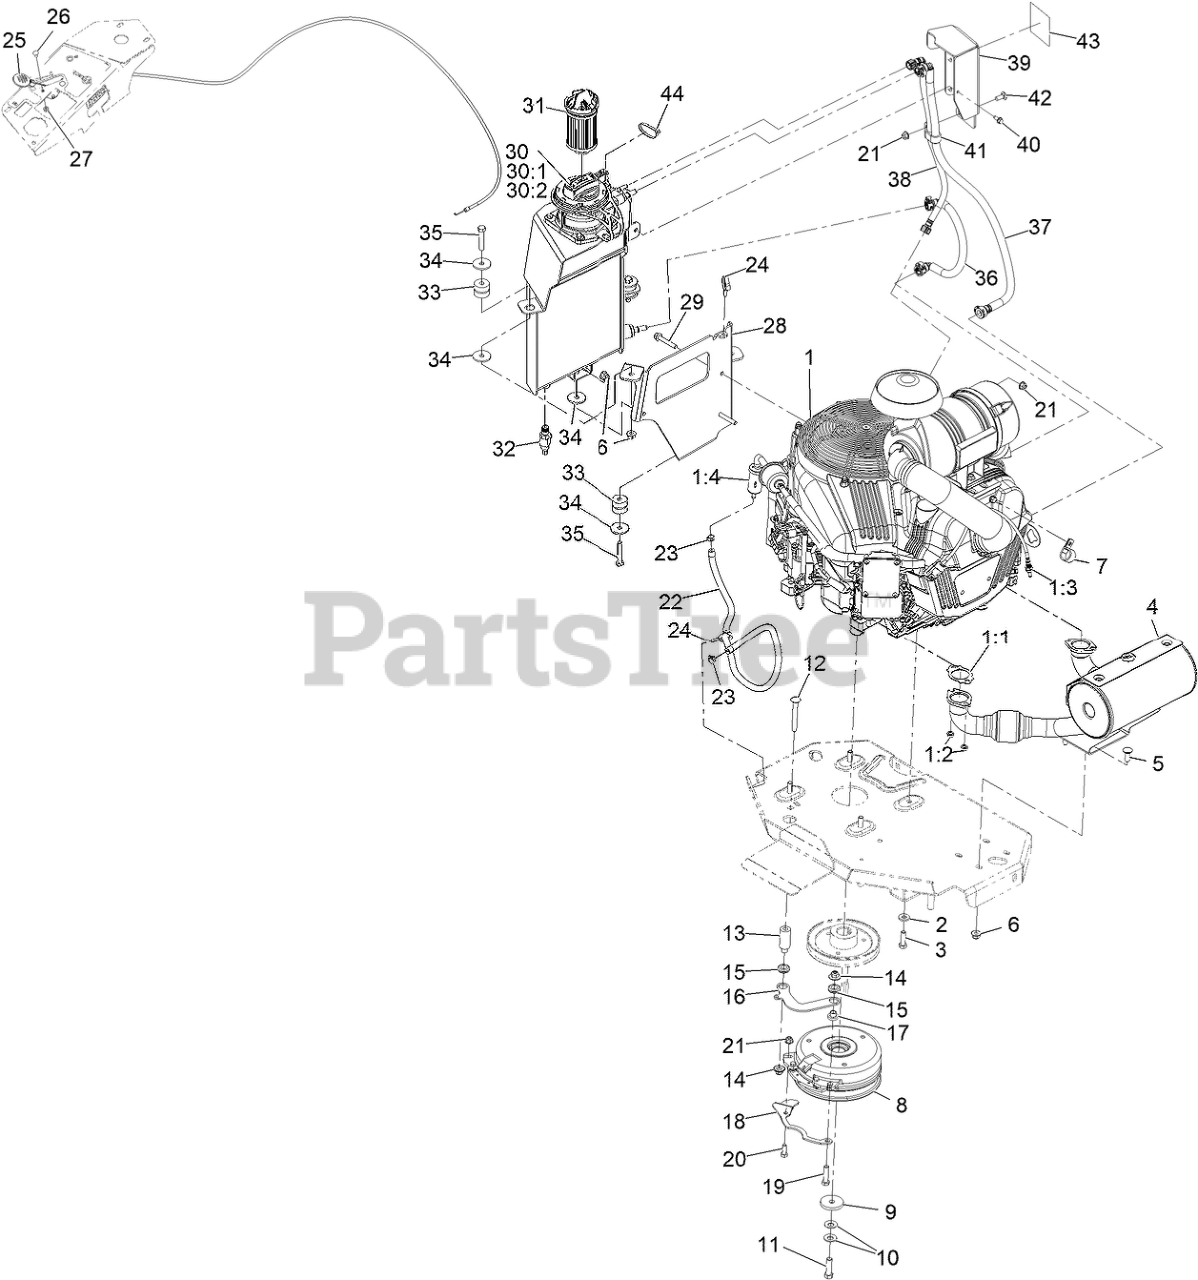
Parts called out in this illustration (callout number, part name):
1	Engine-Vanguard
1:1	GASKET-EXHAUST
1:2	NUT-HEX
1:3	SENSOR-O2
1:4	FILTER-FUEL
2	WASHER-BELLEVILLE
3	SCREW-HH
4	MUFFLER
5	SCREW-CARR
6	NUT-HF, NI
7	R-CLAMP
8	CLUTCH KIT
9	WASHER-CLUTCH
10	WASHER-SPRING
11	SCREW-HH 7/16-20 X 1 1/2 W/LOCTITE
12	SCREW-CARR
14	Nut-Nyloc 3/8-16 Flg
15	GROMMET-RUBBER
16	LINK-ANCHOR, CLUTCH
18	BELT-GUIDE
19	SCREW-HH
20	SCREW-HH
21	NUT-HF, NI
22	HOSE-FUEL
23	CLAMP-HOSE
24	CLAMP-HOSE
25	ASM,THROTTLE CABLE
26	BOLT-CARR
27	NUT-LOCK, NI
28	MOUNT-TANK, OIL
29	SCREW-HHF
30	RESERVOIR-OIL
30:1	OIL DIPSTICK ASM
30:2	OIL TANK CAP ASM
31	FILTER-OIL
32	VALVE-OIL DRAIN
33	ISOLATOR-TANK
35	SCREW-HH
36	HOSE-SUPPLY
37	HOSE-SCAVENGE
38	HOSE-VENT
39	GUARD-HOSE
40	SCREW-HWH
42	SCREW-CARR
43	DECAL-OIL GUARD
44	TIE-CABLE
